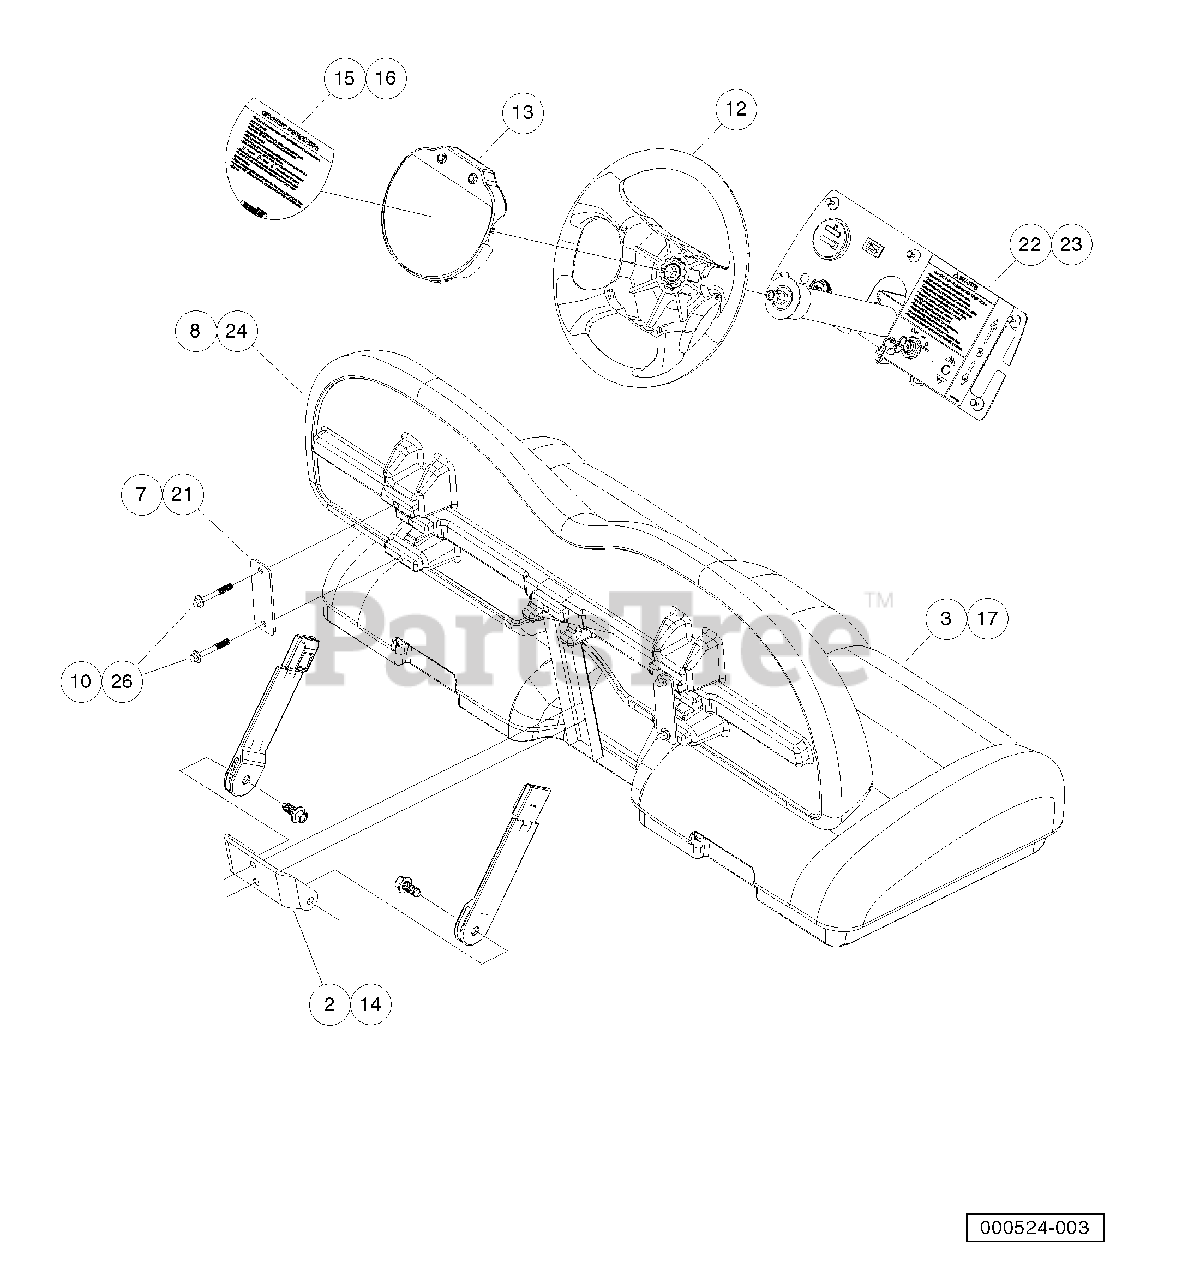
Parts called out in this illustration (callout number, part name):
1	Kit, Bench Seat, Seat Only
2	Bracket, Seat Belt, Bench
3	Asm, Seat Bottom, Bench, Gray
4	Hinge Plate
5	Asm, Seat Bottom, Bench
6	Bolt Flg Blk, M8 X 25, Loctite
7	Bracket, Seat Back, AWD
8	Seat Back, Bench, Gray
9	Instructions, Bench Seat
10	Bolt Flg Blk, M8 X 55, Loctite
11	Kit, Bench Seat, Complete
12	Steering Wheel, Comfort Grip, Hex
13	Center, Plate, Steering Wheel
14	Bracket, Seat Belt, Bench
15	Decal, Oper Instr, Awd Se Dsl
16	Decal, Oper Instr, Awd Se Gas
17	Asm, Seat Bottom, Bench, Gray
18	Hinge Plate
19	Asm, Seat Bottom, Bench
20	Bolt Flg Blk, M8 X 25, Loctite
21	Bracket, Seat Back, AWD
22	Decal, Warning, Iinstrument Panel, AWD Gas
23	Decal, Warning, Iinstrument Panel, AWD Diesel
24	Seat Back, Bench, Gray
25	Instructions, Bench Seat
26	Bolt Flg Blk, M8 X 55, Loctite
